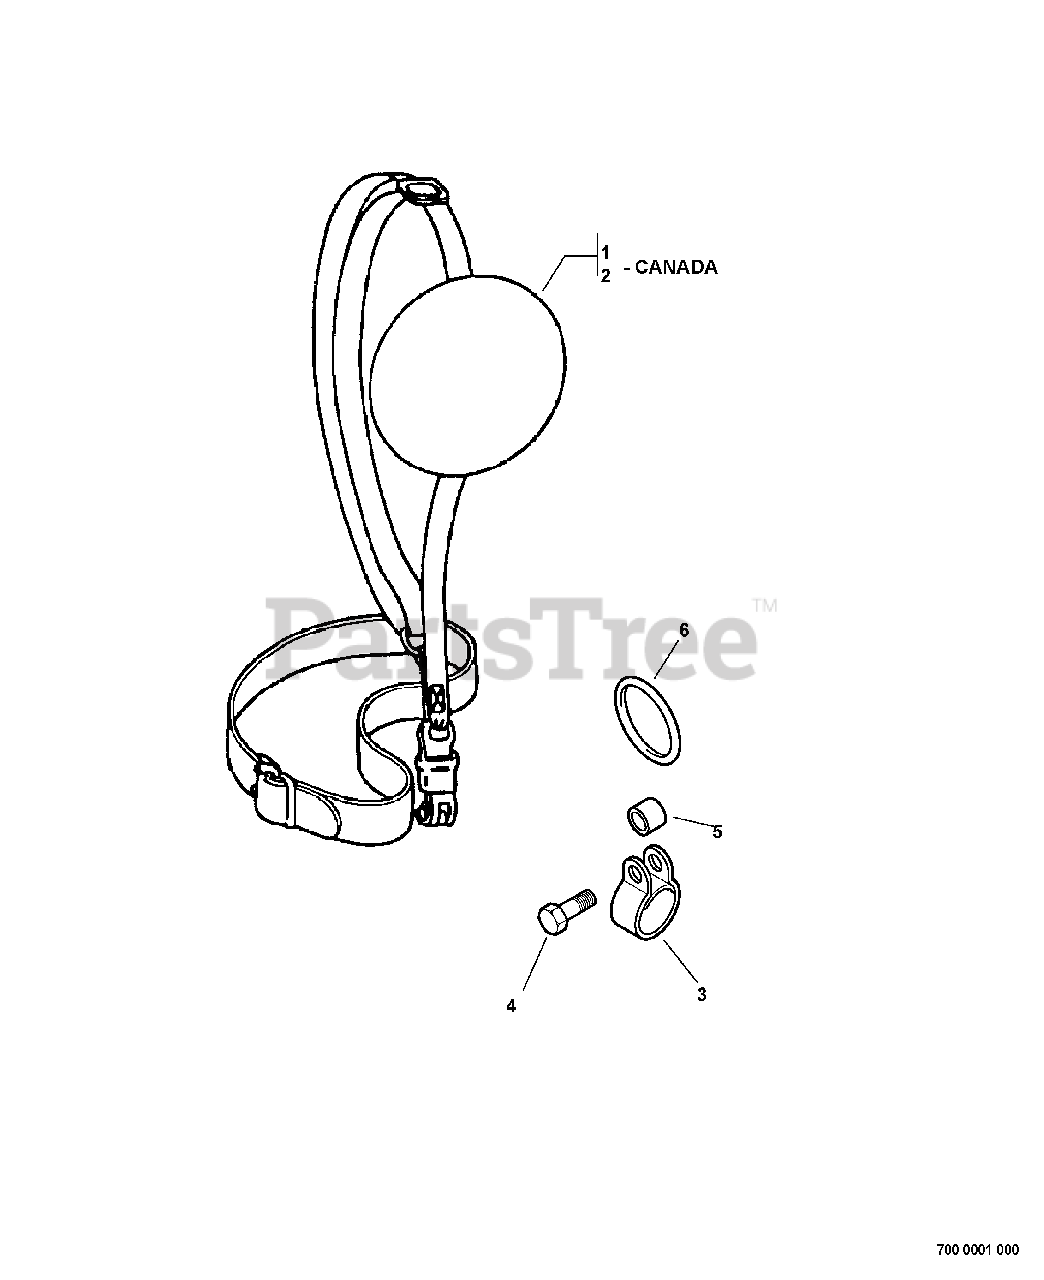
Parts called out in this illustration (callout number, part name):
1	HARNESS, SHOULDER
2	HARNESS, SHOULDER
4	BOLT 5×18
5	SPACER, GUARD
6	RING, HARNESS Ø32
